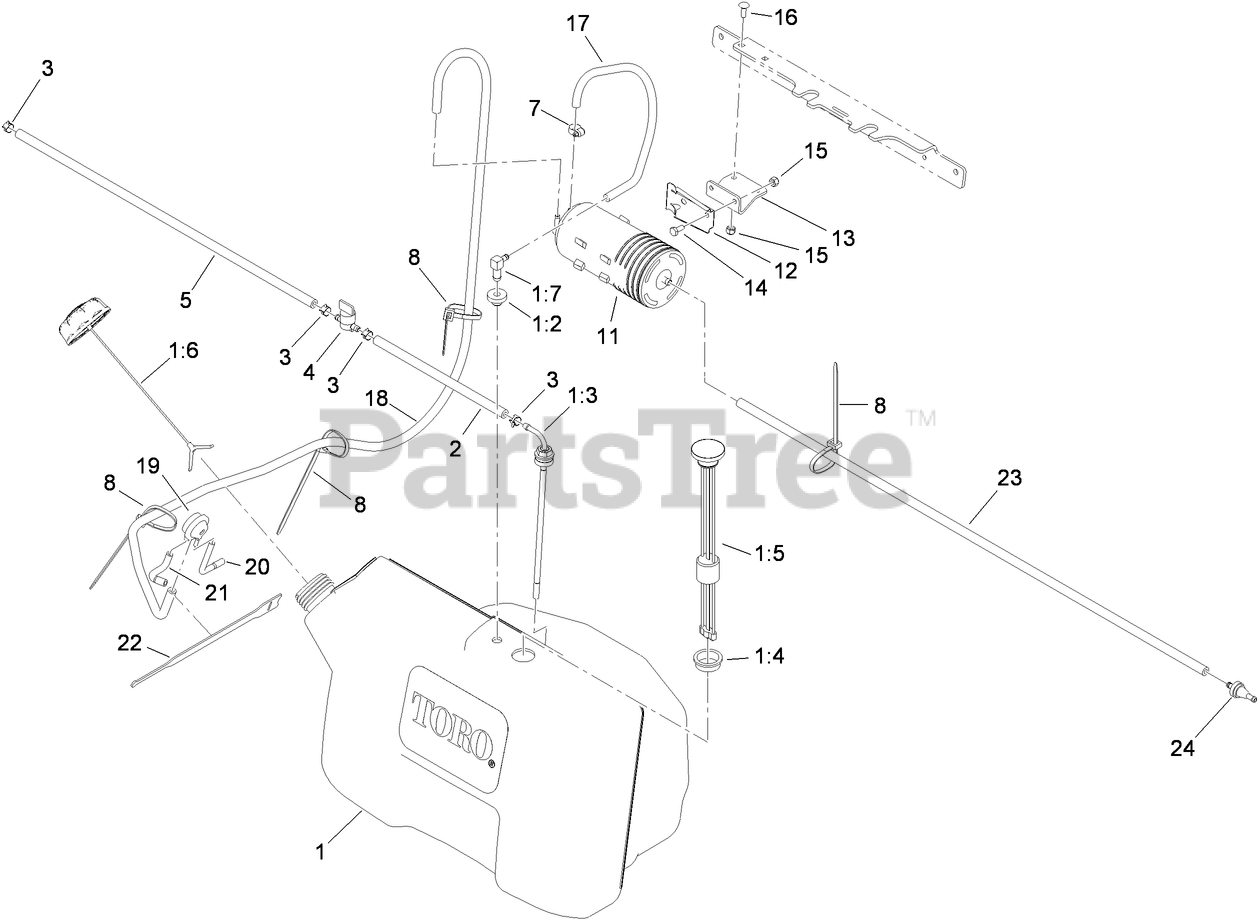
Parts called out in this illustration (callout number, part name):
1	TANK ASM
1:2	BUSHING
1:3	FITTING-FUEL, BULKHEAD
1:4	GROMMET
1:5	GUAGE-FUEL
1:6	CAP-FUEL, RATCHETING
1:7	ELBOW-90 DEG
2	HOSE-FUEL
3	CLAMP-HOSE
4	VALVE-FUEL
5	HOSE-FUEL
7	CLAMP-WORM
8	TIE-CABLE
11	CANISTER-CARBON, 800CC
12	BRACKET-CANISTER, CARBON
13	BRACKET-CANISTER
14	SCREW-HH
15	NUT-LOCK, NI
16	BOLT-CARR
17	HOSE-FUEL
18	HOSE, VACUUM
19	VALVE-CONTROL, VACUUM
20	HOSE-VENT, FORMED
21	HOSE-VENT, FORMED
22	STRAP-VELCRO, CABLE TIE
23	HOSE-FUEL
24	FILTER-FUEL
